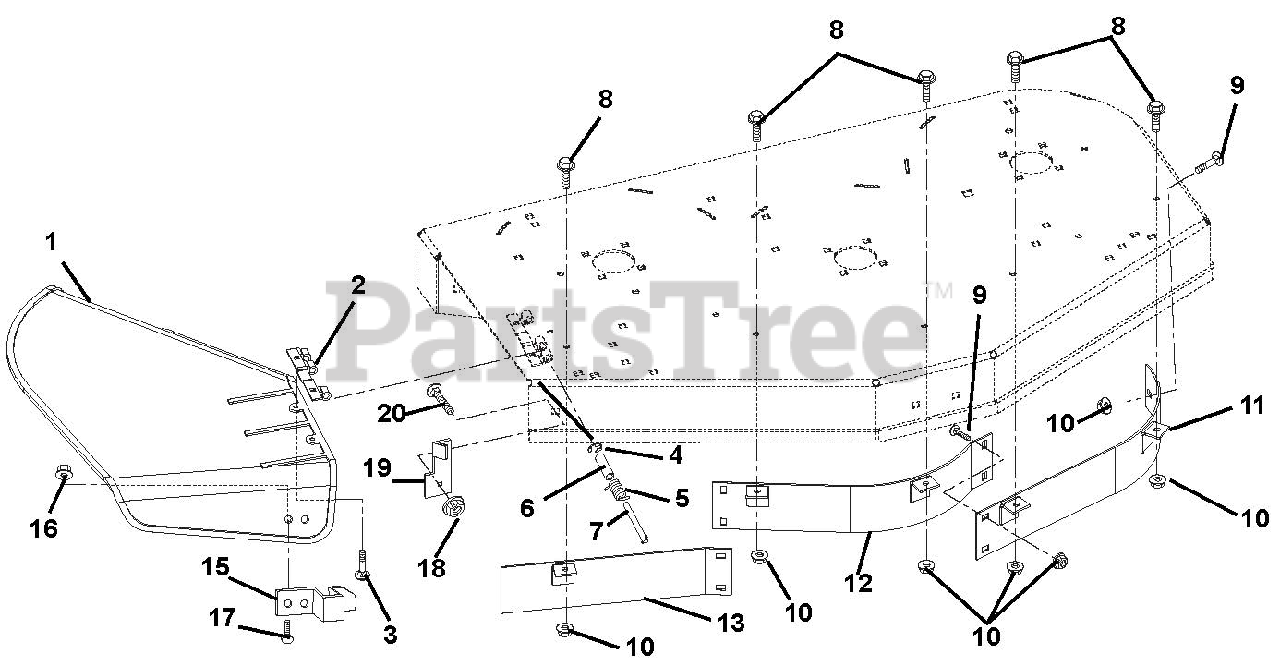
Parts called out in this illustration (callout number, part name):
1	DEFLECTOR, CHUTE
2	HINGE PLATE
3	@BLT-RDHDSQNK .25-20X.75 G5YZ
4	RG-RTNG-EXT .312X.025
5	SG-TORS .095X.50X 1.0
6	BSHG-SLV .334 X .502 X 1.437
8	BLT-SERHFWH .312-18X.75 YWZC
9	@BLT-RHDSSQNK .31-18X.62 G5YZ
10	@NUT-LK-NYL-FLG .31-18 YWZC
11	BAFFLE - LEFT FRONT - 40"
12	BAFFLE - CENTER FRONT - 40"
13	BAFFLE - RIGHT FRONT - 40"
14	DEFLECTOR-40"
15	FLAT SPRING
16	@NUT-LK-TOP-FLG .25-20 YWZC
17	@BLT-RDHDSQNK .25-20X.50 G5YZ
18	@NUT-LK-NYL-FLG .38-16 YWZC
19	BRACKET, CHUTE LOCK
20	@BLT-RDHDSQNK .38-16X1.50 G5YZ
